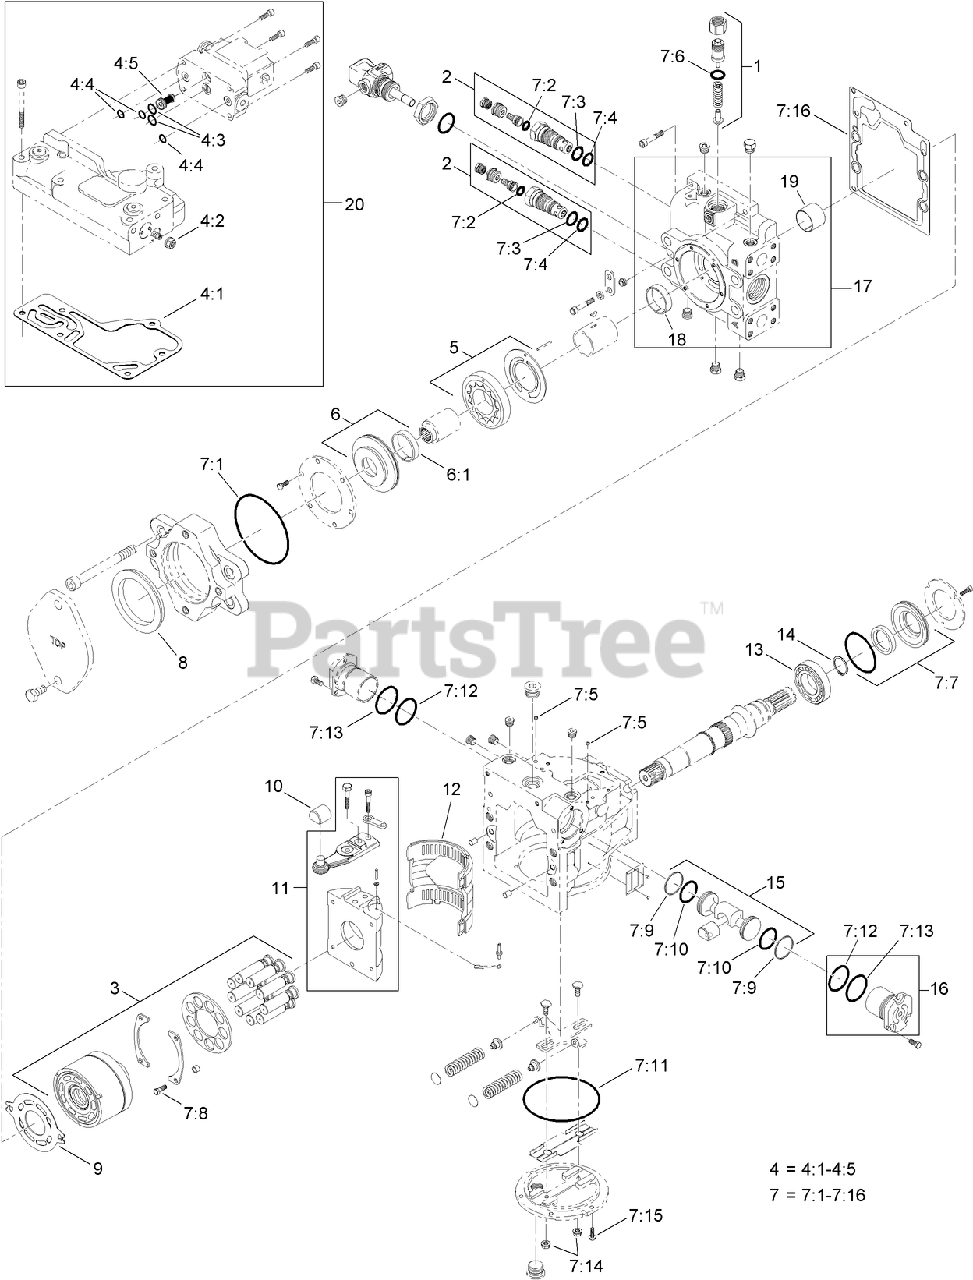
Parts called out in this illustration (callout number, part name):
1	CHARGE RELIEF VALVE KIT
2	MULTI-FUNCTION VALVE KIT
3	CYLINDER BLOCK KIT
4	CONTROL SEAL KIT
4:1	GASKET-CONTROL
4:2	NUT-SEAL
4:3	O-RING
4:4	O-RING
4:5	FILTER ASM
5	CHARGE PUMP SET
6	CHARGE PUMP COVER ASM
6:1	BUSHING
7	BASE PUMP SEAL KIT
7:1	OBS O-RING
7:2	O-RING
7:3	O-RING
7:4	O-RING
7:5	SCREEN-CONTROL FILTER
7:6	O-RING
7:7	SHAFT SEAL ASM
7:8	Screw
7:9	O-RING
7:10	O-RING
7:11	O-RING
7:12	O-RING
7:13	O-RING
7:14	NUT
7:15	Screw
7:16	Gasket-End Cap
8	SEAL-B PAD
9	PLATE-VALVE
10	BLOCK-SLIDER
11	SWASHPLATE ASM
12	BEARING ASM
13	BEARING-ROLLER
14	RING-RETAINING
15	SERVO PISTON KIT
16	SERVO CYLINDER ASM
17	END CAP ASM
18	BUSHING
19	BEARING-JOURNAL
20	EDC KIT
